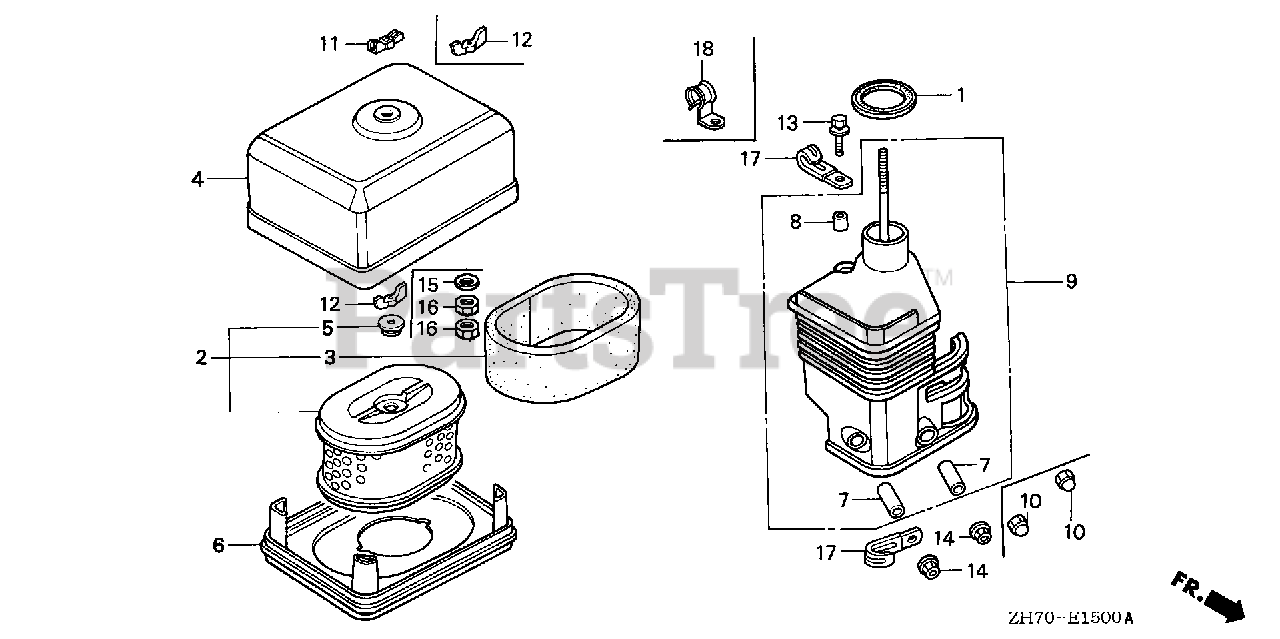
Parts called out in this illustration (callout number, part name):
1	GASKET, ELBOW
2	ELEMENT, AIR CLEANER (DUAL)
3	FILTER (OUTER)
4	COVER, AIR CLEANER (DUAL)
5	GROMMET, AIR CLEANER
7	COLLAR, AIR CLEANER
8	COLLAR B, AIR CLEANER
9	ELBOW, AIR CLEANER
12	NUT, TOOL BOX SETTING
13	BOLT, FLANGE (6X20)
14	NUT, FLANGE (6MM)
15	WASHER, PLAIN (6MM)
